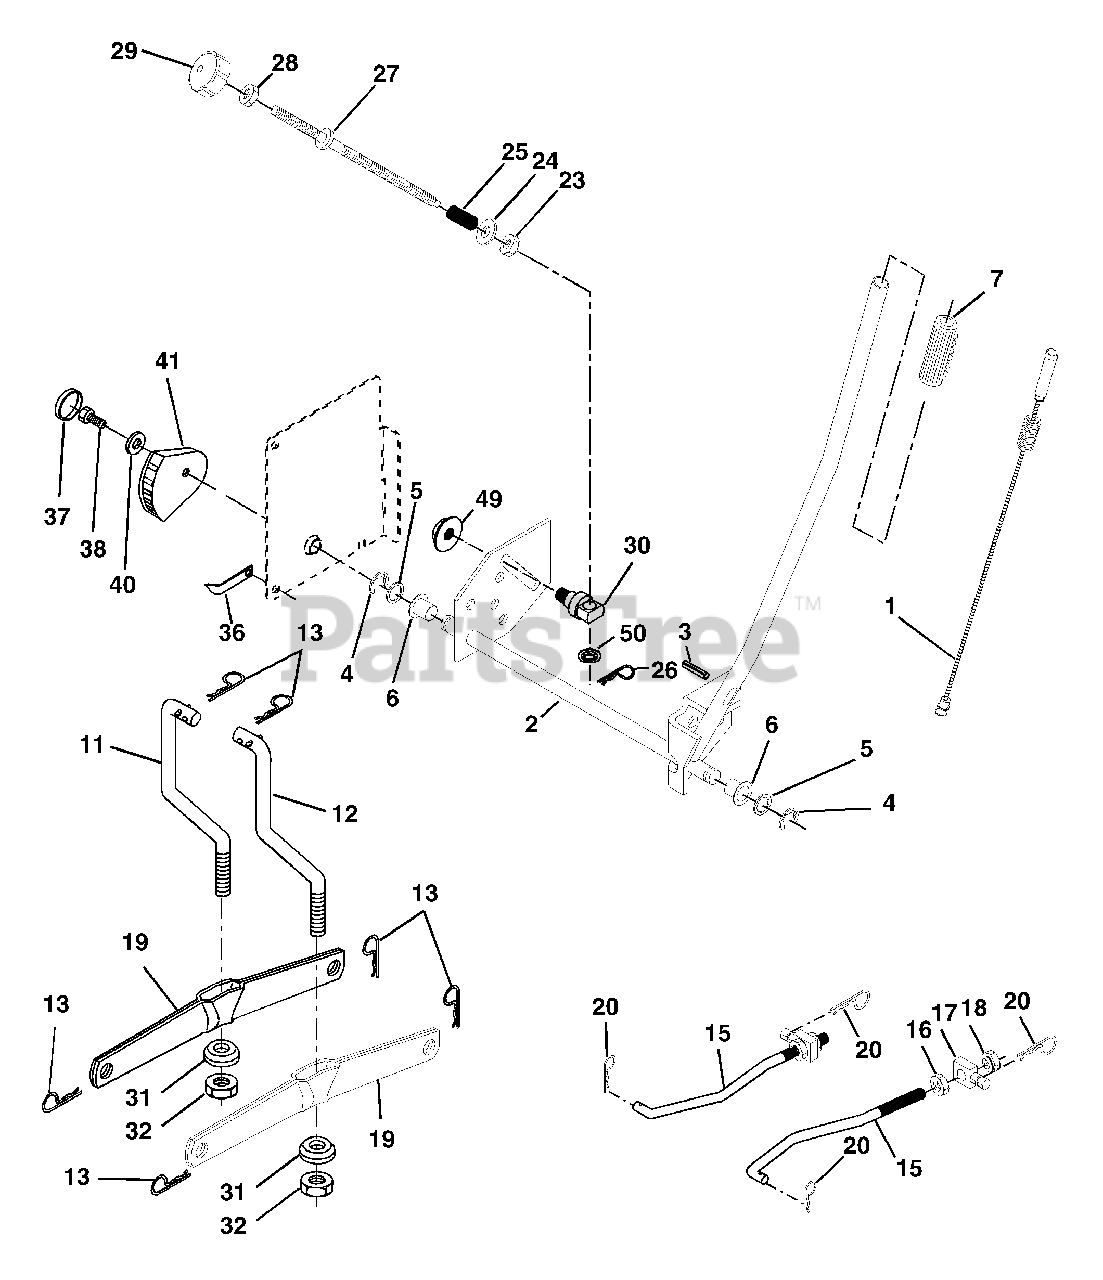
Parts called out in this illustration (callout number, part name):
1	Plunger Asm.
2	Shaft Asm Lift
3	Pin Groove
4	E Ring #5133-62
5	Washer 21/32 x 1 x 21 Ga.
6	Bearing Nylon
7	Grip Handle
11	Link Lift Lh
12	Link Lift Rh
13	Retainer Spring
15	Link Front
16	Nut Jam Hex 1/2-13 Unc
17	Trunnion Blk Zinc
18	Nut Lock w/Wsh 1/2-13 Unc
19	Arm Suspension Rear
20	Retainer Spring
23	Nut Special
24	Washer 13/32 x 5/8 x 16 Ga.
25	Spring
26	Retainer Clip
27	Rod Adj. Lift
28	Nut Hex Jam 3/8-16 Unc
29	Knob
30	Trunnion Infin. Height
31	Bearing Pvt Lift
32	Nut Crownlock 3/8-24
36	Pointer Height Indicator
37	Plug Hole
38	Screw 5/16-18 x 1
40	Washer 11/32 x 1-1/2 10 Ga.
41	Indicator Height
49	Nut Hex Flange Lock
50	Nut Push
